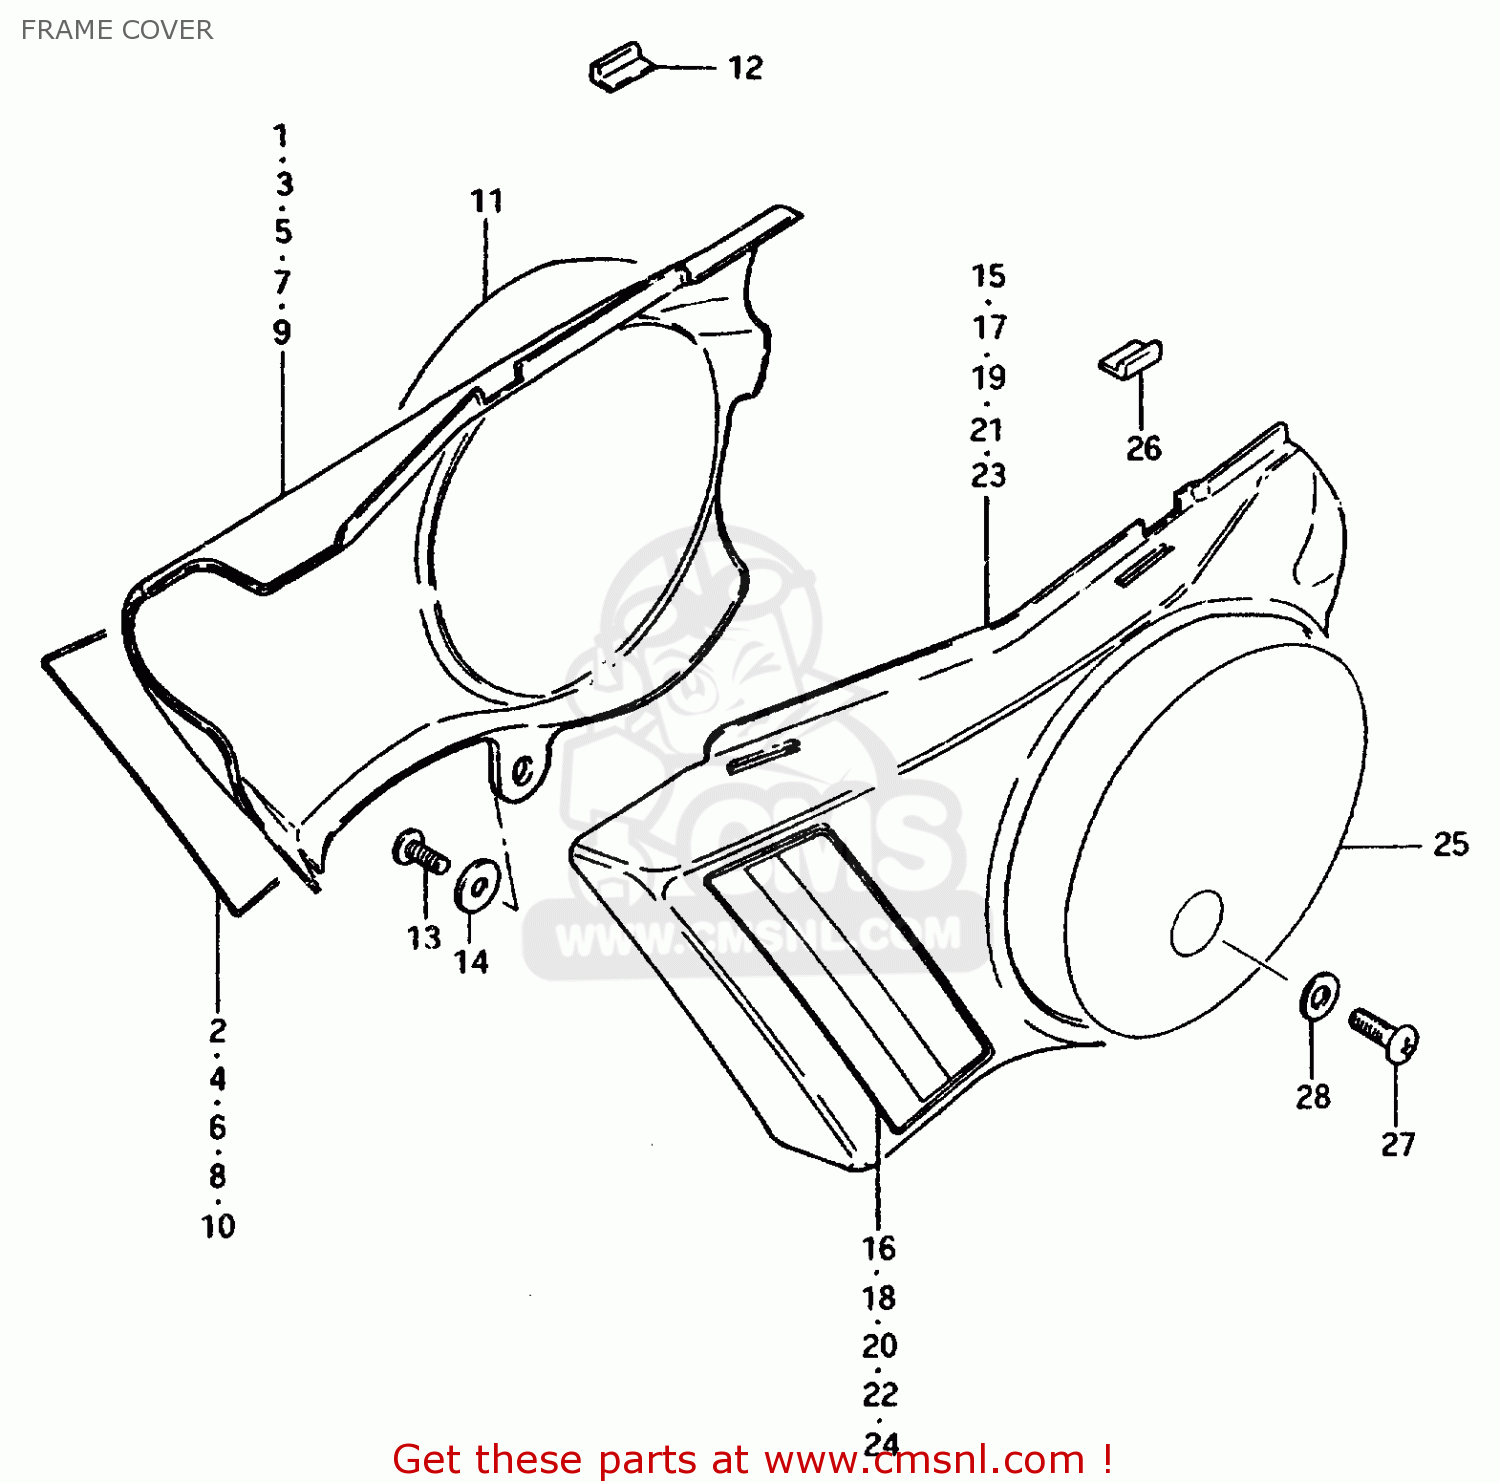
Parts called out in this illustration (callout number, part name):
1	COVER, FRAME RH (RED)
2	TAPE, STRIPING RH
3	COVER,FRAME RH
4	TAPE, STRIPING RH
5	COVER,FRAME RH
6	TAPE, STRIPING RH
7	COVER, FRAME RH (BLUE)
8	TAPE, STRIPING RH
9	COVER,FRAME RH
10	TAPE, STRIPING RH
11	EMBLEM, RH
12	CUSHION,FRAME COVER
13	SCREW 6X12
14	WASHER
15	COVER, FRAME LH (RED)
16	TAPE, STRIPING LH
17	COVER, FRAME LH (BLUE)
18	TAPE, STRIPING LH
19	COVER, FRAME LH (WHITE)
20	TAPE, STRIPING LH
21	CVOER, FRAME LH (BLUE)
22	TAPE, STRIPING LH
23	COVER, FRAME LH (YELLW)
24	TAPE, STRIPING LH
25	EMBLEM, LH
26	CUSHION,FRAME COVER
27	SCREW
28	WASHER
